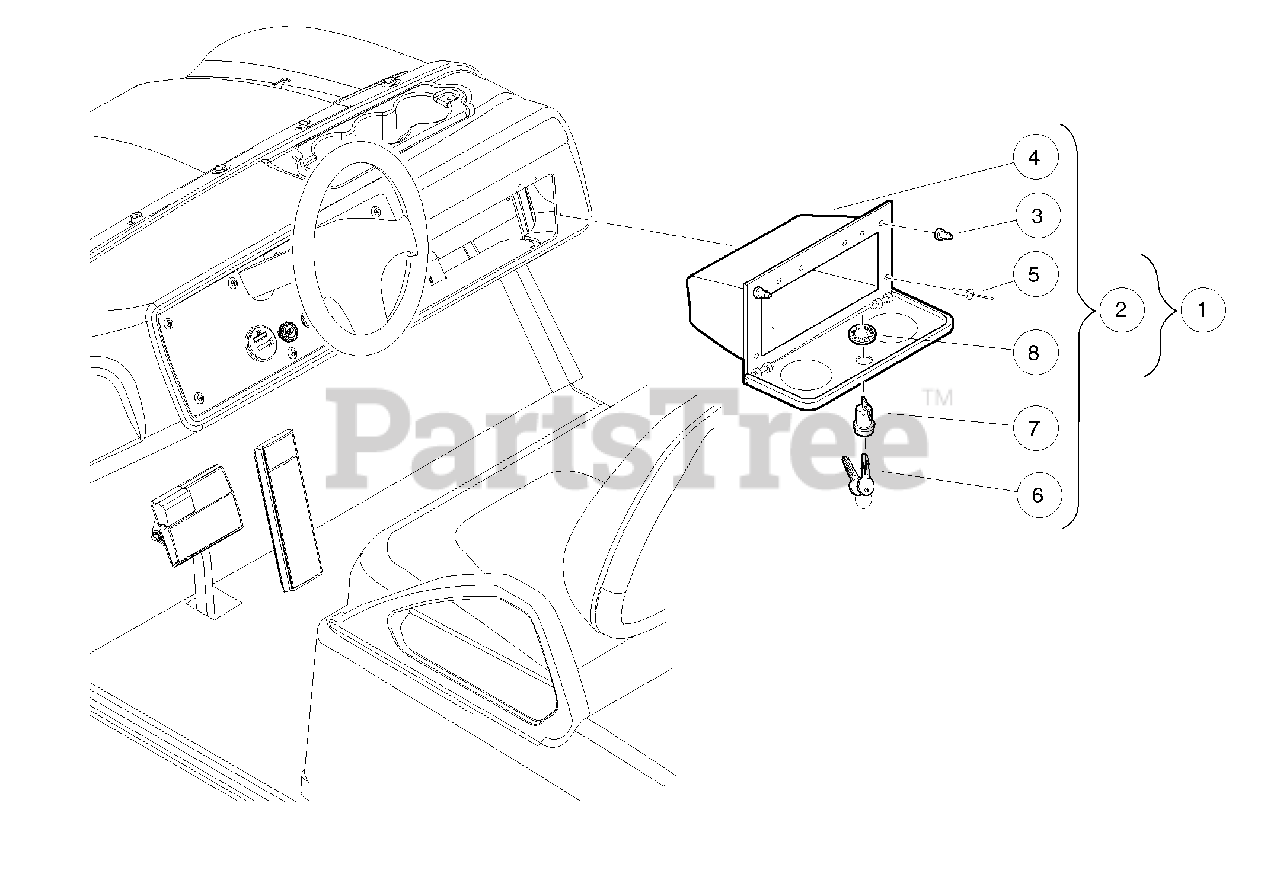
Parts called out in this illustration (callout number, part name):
1	Glove Box Lock / Key Kit
2	Asm, Glove Box Lock / Key
3	Bumper, Rubber
6	Key
7	Lock
8	Nut
